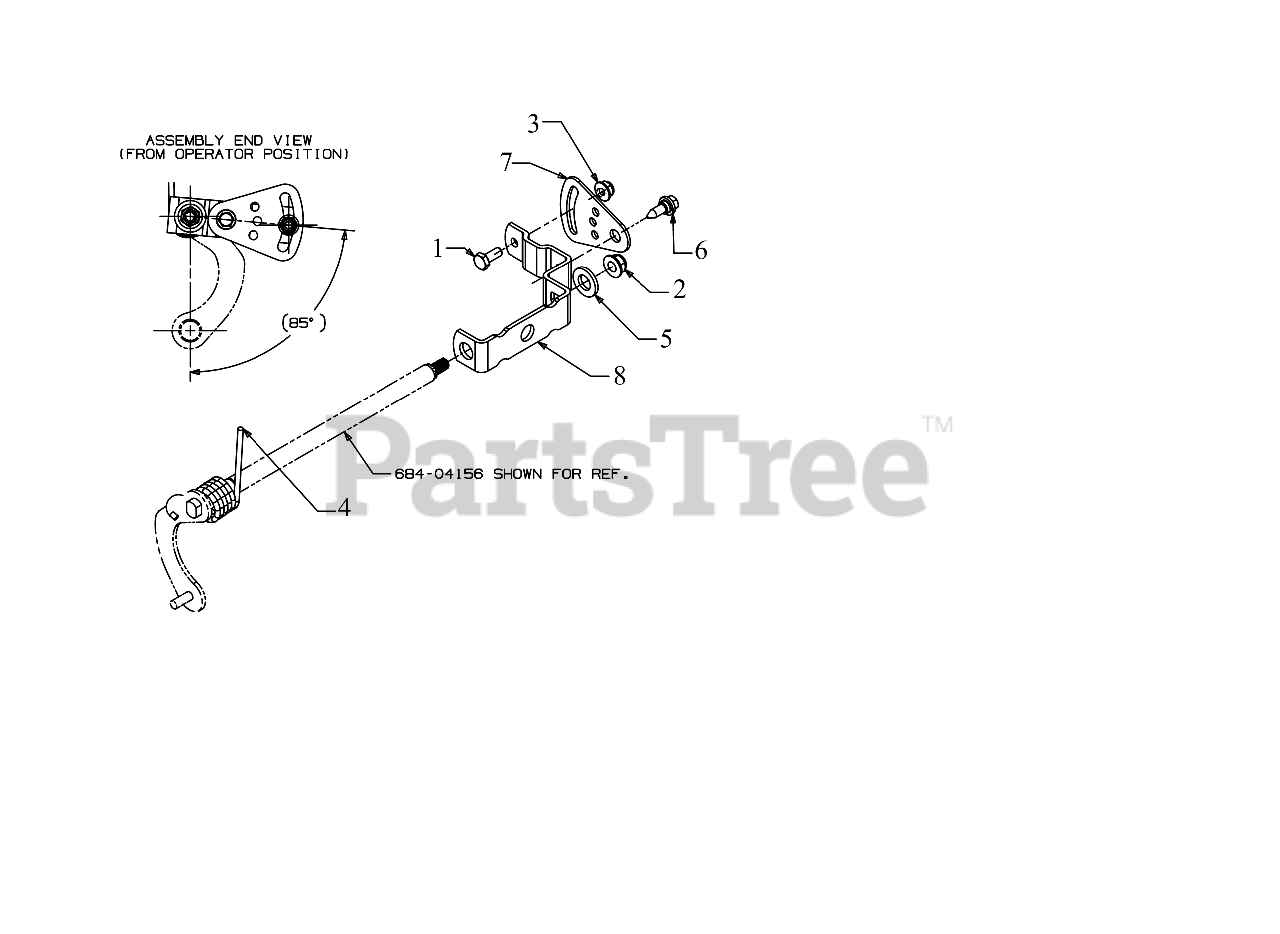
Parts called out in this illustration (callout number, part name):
1	SCREW 1/4-20 x .620 GR5
2	FLANGE LOCK NUT 5/16-18
3	FLANGE LOCK NUT
4	TORSION SPRING
5	FLAT WASHER
6	SHOULDER SCREW
7	PIVOT BRACKET
8	SHIFT SPEED BRACKET
